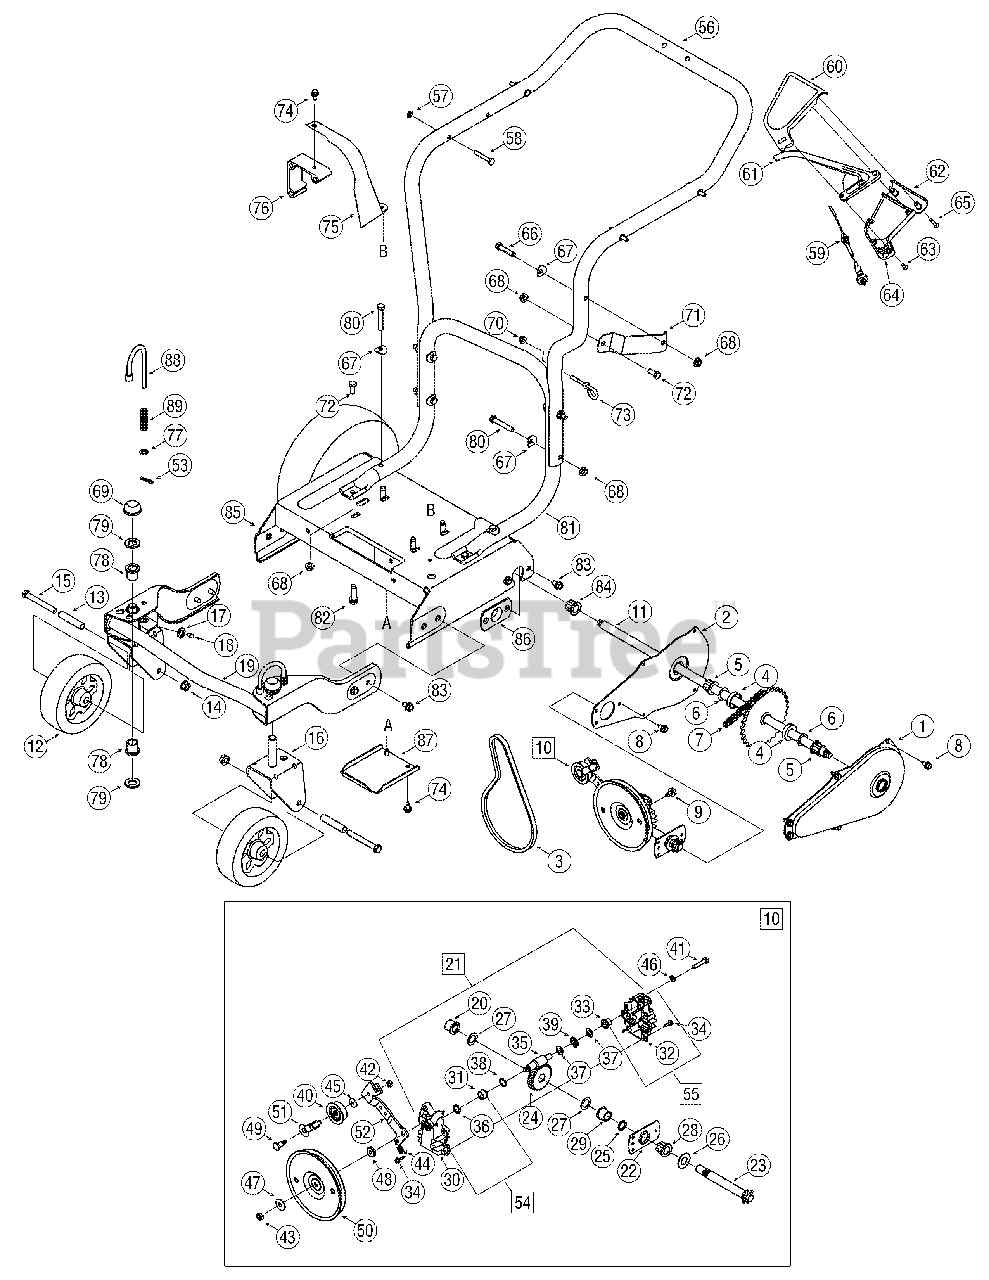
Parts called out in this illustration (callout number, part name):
3	V-Belt
5	Hex Flange Bearing
6	Flat Washer
7	Chain
8	TT Screw 1/4-14 x 0.625"
9	Hex Washer Screw 5/16
10	Chipper Shredder Trans. Ass’y.
11	Axle Assembly
12	Wheel 6.0 x 2.0
14	Flange Lock Nut 3/8-16
15	Hex Cap Screw 3/8-16 x 3.0
17	Flat Washer.203 ID x.403 OD
18	Grease Fitting 3/16
20	Flange Bearing.566 ID
21	Shredder Transmission Assembly
23	Output Shaft 6T Sprocket
24	Helical 34T Gear
26	Flat Washer.64 ID x 1.24 OD
27	Flat Washer 5/8 x 1.0
28	Hex Flange Bearing.631 ID
29	Flange Bearing.629 ID
30	Lower Housing
31	Flange Bearing.503 ID
32	Upper Housing
33	Flange Bearing.378 ID
34	Hex Washer Screw #10-16 x.75
35	Pinion Shaft 10T
36	Oil Seal
37	Thrust Washer.382 ID x.684 OD
38	Flat Washer.504 ID x.70 OD
39	Thrust Bearing.375 ID x.812 OD
40	Idler Pulley Assembly W/ Bearing
40	Idler Pulley Only
40	Needle Bearing Only
41	Hex Cap Screw 1/4-20 x 1.25
42	Hex Nut 1/4-28
43	Hex Jam Nut 5/16-24 LH Thd
44	Extension Spring 1.12 Lg
45	Bell Washer.265 ID x.75 OD
46	Lock Washer 1/4
47	Bell Washer.325 ID x.930 OD
48	Shoulder Spacer.375 ID x.165 OD
49	Shoulder Bolt 1/4-28 x.375
50	Flat Pulley 5.06 Dia
51	Belt Keeper
52	Idler Bracket
53	Cotter Pin
54	Lower Housing Assembly
55	Upper Housing Assembly
58	Stud Pin.250 x 1.75
59	Clutch Cable 56"
60	Upper Clutch Cover
61	Drive Lever
62	Lower Clutch Cover
63	Screw #10-12 x.750
64	Mounting Cable Cap
65	Screw #10-16 x 1.25
66	Hex Cap Screw 5/16-18 x 1.50
67	Shoulder Washer.320 ID x.93 OD
68	Hex Flange Lock Nut 5/16-18
70	Hex Nut 1/4-28
72	Hex Cap Screw 5/16-18 x.75
74	Hex Washer Screw 1/4-14 x.625
75	Belt Cover
76	Engine Mounting Adapter
77	Flat Washer.330 ID x.630 OD
78	Flange Bearing.632 ID
79	Flat Washer 5/8 ID x 1.0 OD
80	Hex Cap Screw 5/16-18 x 1.75
82	Screw 3/8-16 x 1.25
83	Hex Washer Screw 5/16-18 x.625
84	Hex Flange Bearing.631 x.720
89	Compression Spring
